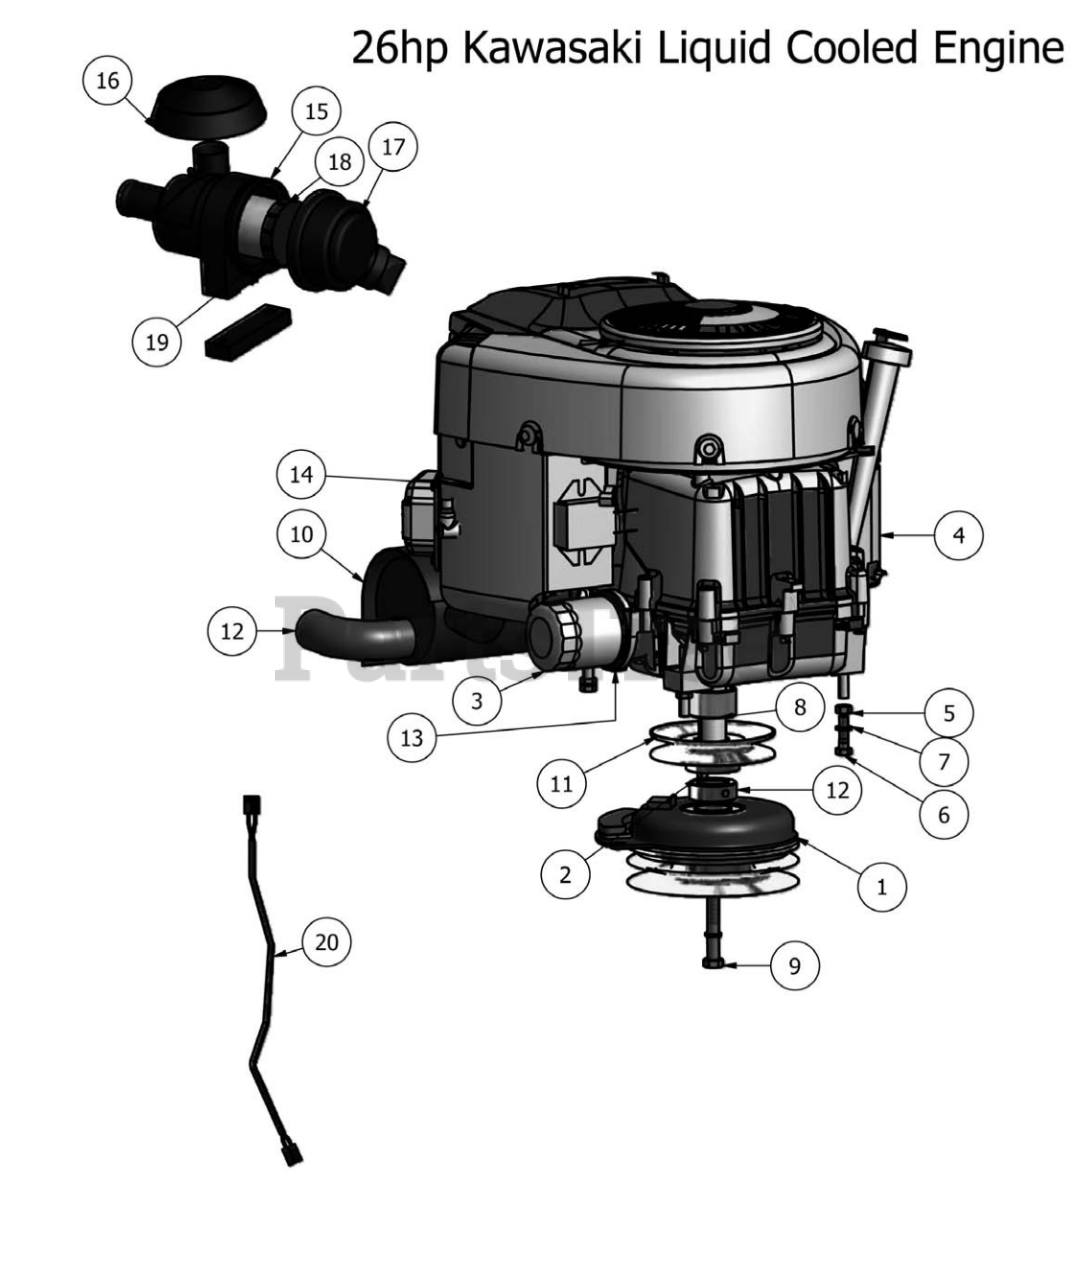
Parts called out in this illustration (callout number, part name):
2	1/4" x 1" Key
3	26 HP Oil Filter
4	26 HP Engine
5	5/16" Hex Nut
6	5/16" x 1 1/4" Hex Bolt
7	5/16" Lock Washer
8	1 1/8" Collar Spacer
9	7/16" x 2 1/2" Hex Bolt
10	26 HP Exhaust
11	4 3/4" Motor Pulley
12	1 1/8" Pulley Spacer
13	Oil Drain Valve
14	Fuel Filter
15	26hp Kawasaki Complete Canister
16	Rain Cap 26hp Kawasaki
17	Filter End Cap
18	Air Filter-Outer
19	Air Filter-Inner
20	Clutch Pigtail
